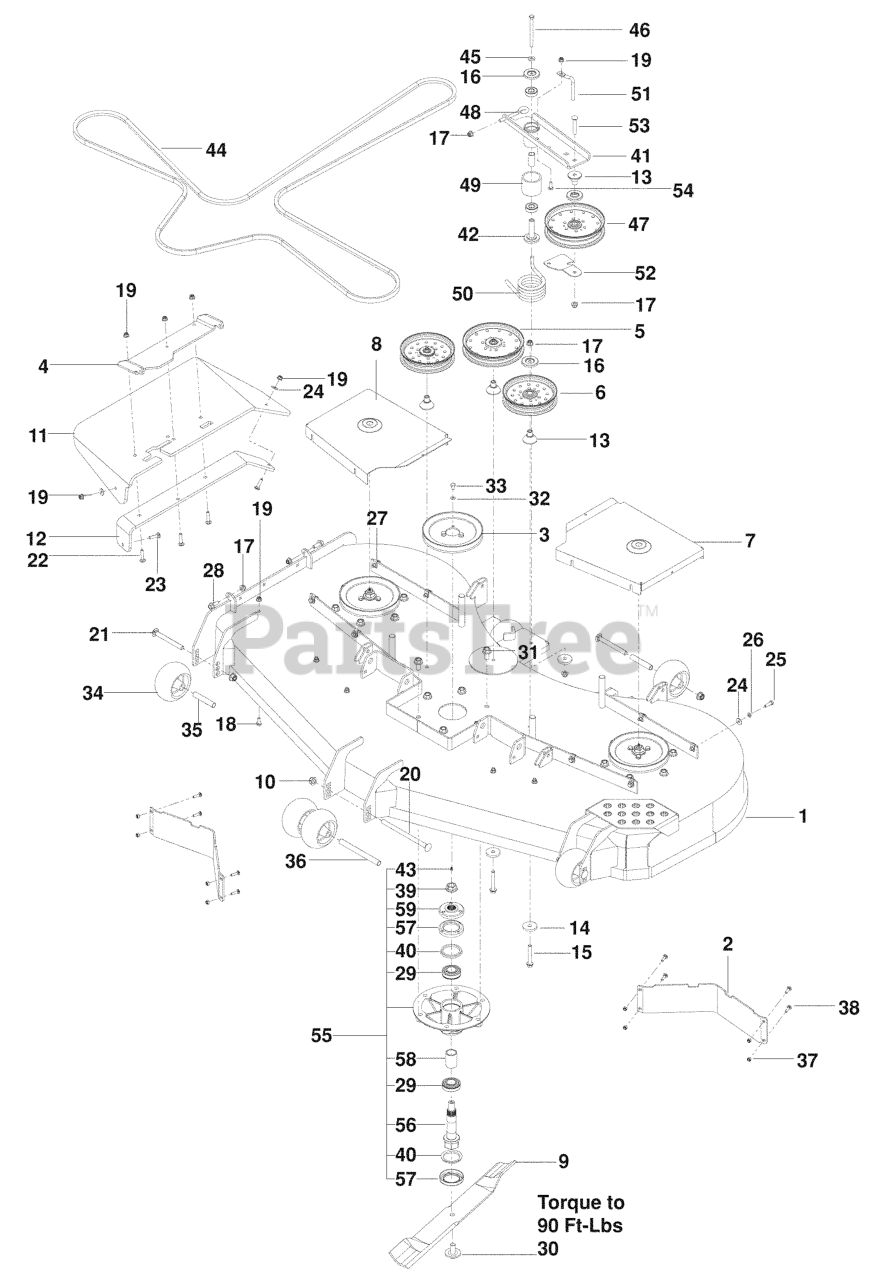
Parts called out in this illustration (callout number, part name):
1	DECK.SVC.W/DECALS.72.ORANGE.HU
2	BAFFLE, DIVERTER 72" BLACK
3	PULLEY - 7.50
4	BRKT - CHUTE MTG BLACK
5	PULLEY - 7" NARROW
6	PULLEY IDLER, 6" NARROW
7	SHIELD, BELT 72 R.H. ORANGE
8	SHIELD, BELT 72 LH ORANGE
9	BLADE OEM - 25"
10	NUT, 1/2-13 HEX FLG NYLOC ZD
11	CHUTE, DISCHARGE 60-72
12	BRKT - CHUTE SUPPORT BLACK
13	BEARING, IDLER ARM
14	SPINDLE WASHER
15	HHFS 3/8-16 X 2 3/4
16	DUST SHIELD
17	NUT 3/8-16 HEX FLG NYLOC ZD
18	HHFS 5/16-18 X 3/4
19	5/16-18 NYLOC FLANGE NUT
20	RHSNB 1/2-13 X 8 GR5 ZD
21	RHSNB 1/2-13 X 4.75 GR5 ZD
22	RHSNB 5/16-18 X 1-1/2 GR 5 ZD
23	BOLT, CARRIAGE 5/16X1-1/4
24	WASHER 5/16 FLAT
25	HCS 5/16C X 1
26	WASHER.LOCK.HVY.HLCL.SPR.5/16
27	U-CLIP 5/16-18 NUT RETAINER
28	HHFS 3/8-16 X 1 GRD 5 ZD
29	BEARING - 206KRR8
30	BLADE BOLT/WASHER
31	HHFS 1/2-13 X 1 GR5 ZD
32	WASH 5/16 DISC SPRING ZD
33	HCS 5/16-18 X 1/2 GR 5 ZD
34	ROLLER, GAUGE .635 BORN
35	TUBE, ROLLER AXLE
36	TUBE, ROLLER AXLE LONG
37	NUT.1/4-20.HEX.NYLOC.ZD
38	RHSNB, 1/4-20 X 1, GR5
39	NUT FLANGE 3/4-16
40	V-RING, 55MM
41	ASSY, IDLER ARM, PZ
42	BEARING, IDLER PIVOT
43	ZERK
44	BELT, "B", 201
45	WASHER, 3/8 THICK
46	HCS 3/8-16 X 4-1/2 GR 8 ZD
47	PULLEY - IDLER 7"
48	EYE BOLT, 3/8 X 4"
49	SPACER, IDLER PIVOT
50	SPRING, TORSION, IDLER
51	BELT KEEPER
52	BELT.GUIDE.BLACK
53	CARRIAGE BOLT 3/8-16 X
54	RHSSNB 5/16C X 1.0
55	SPINDLE ASM. 10"
56	SHAFT - SPINDLE
57	CUP - DEBRIS
58	SPACER - BEARING
59	HUB - PULLEY
